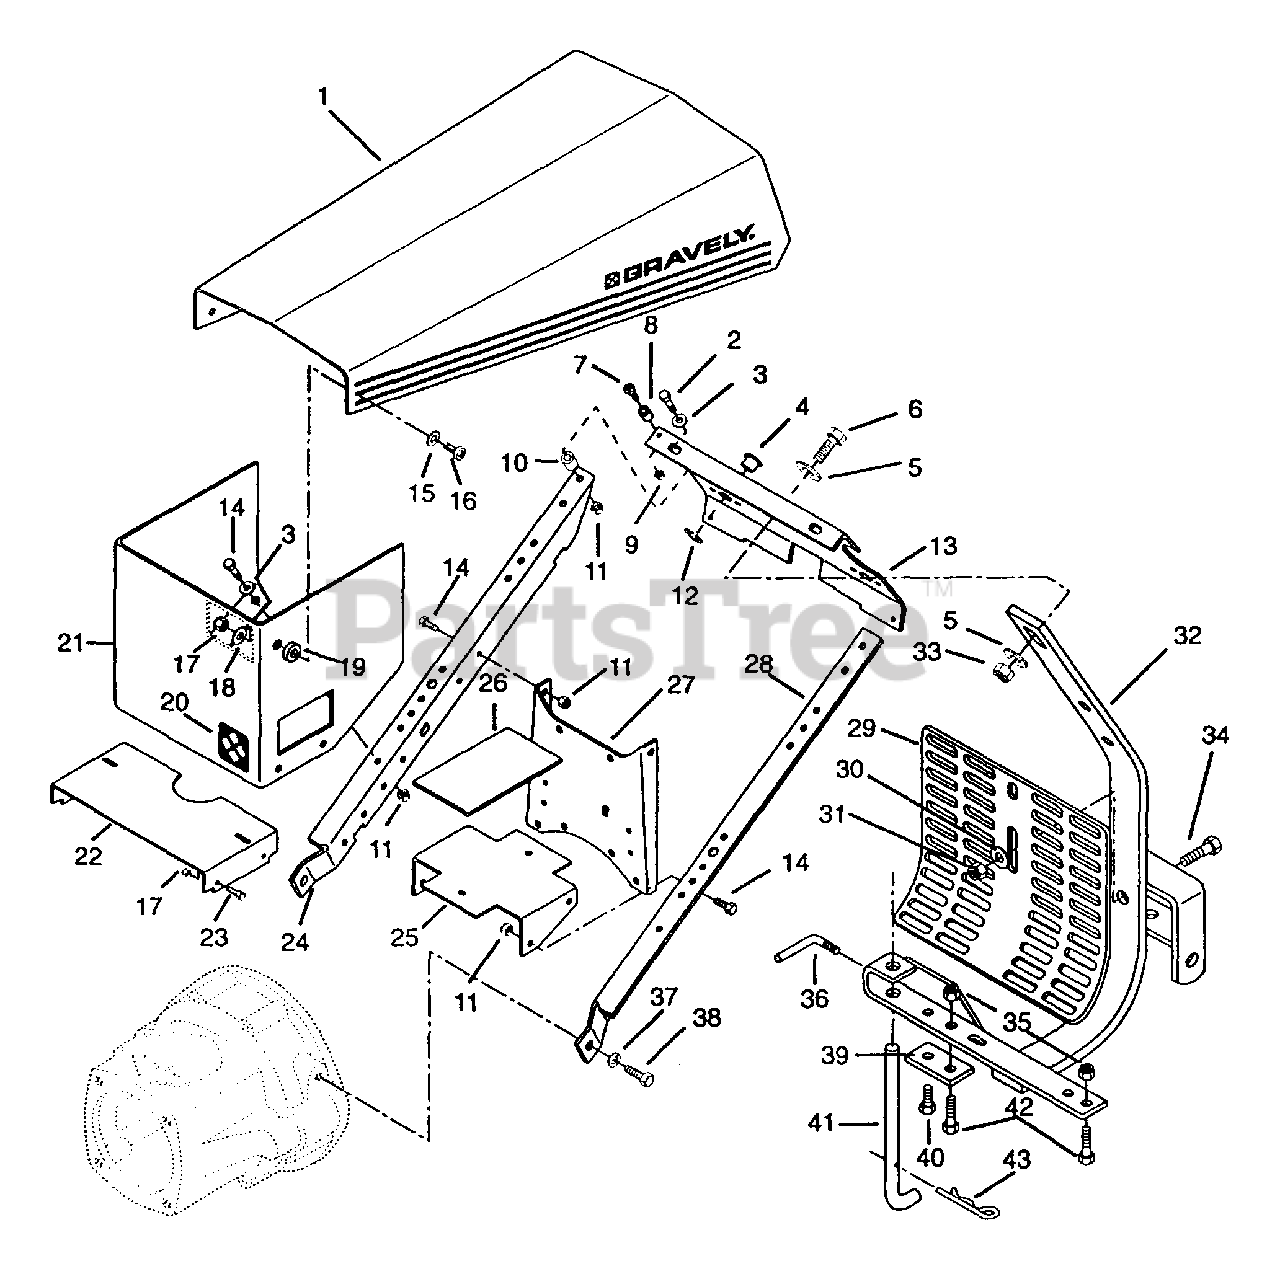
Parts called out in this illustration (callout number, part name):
1	Hood Silk Screen
2	Bolt-Hex .38-16 x 1.50 Grade 5
3	Washer-Flat-Steel .406 x .812 x .065
4	Bushing-Flange .515 x .750 x .745 x 1.00
5	Washer-Flat-Steel .656 x 1.250 x .100
6	Bolt-Hex .625-11 x 2.00
7	Screw-Machine 6-32 x .625
8	Bumper
9	Nut-Locking-Machine 6-32
10	Bushing
11	Nut-Locking-Nylon .375-16 Grade 2
12	Ring-Retaining 1.000 x.748
13	Plate, Silk Screen
14	Bolt-Hex .380-16 x .875
15	Washer-Flat-Steel .281 x .620 x .065
16	Screw-Machine .250-20 x 1
17	Nut-Locking-Nylon .250-20 Grade 2
18	Washer-Flat-Steel .313 x .875 x .065
19	Bushing, Flange 280 x .750 x .318
20	Decal, Comm. Front
21	Support, Hood
22	Bracket
23	Bolt-Hex .25-20 x .63
24	Support, Handle Bar Right Hand
25	Bracket, Tank Support
26	Pad, Gas Tank
27	Bracket
28	Support, Handle Bar Left Hand
29	Guard, Engine
30	Washer-Flat-Steel .531 x 1.250 x .100
31	Nut-Locking-Nylon .50-13 Grade 5
32	Weldment, Hitch
33	Nut-Locking-Nylon .625-11 Grade 2
34	Bolt-Hex .50-13 x 1.50 Grade 5
35	Nut-Locking-Nylon .312-18 Grade 2
36	Handle, Adjusting
37	Washer-Lock.50 Reg.
38	Bolt-Hex .50-13 x 1 Grade 5
39	Bracket
40	Bolt-Hex .31-18 x 1.00 Grade 5
41	Stand, Kick
42	Bolt-Hex .31-18 x 2.00 Grade 5
43	Pin-Hair-Internal .15 x 2.937
